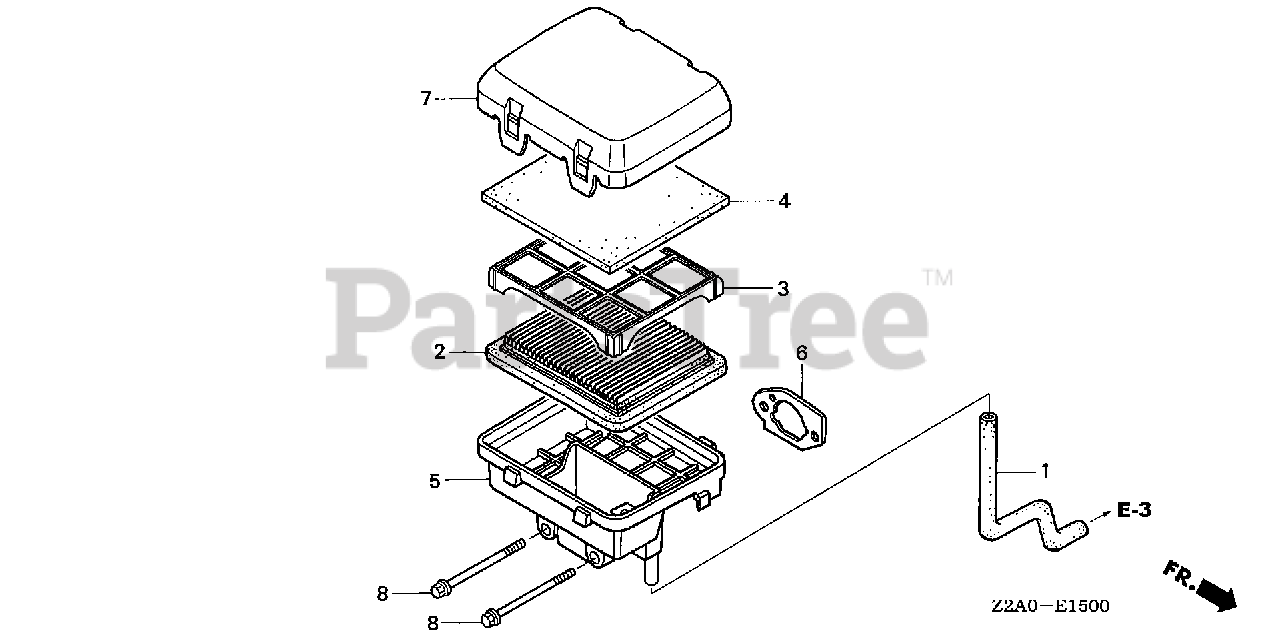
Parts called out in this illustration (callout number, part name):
1	TUBE, BREATHER
2	ELEMENT, AIR CLEANER (TOYO ROKI)
3	GRID, AIR CLEANER
4	FILTER (OUTER) (WET)
5	HOUSING, AIR CLEANER
6	GASKET, AIR CLEANER
7	COVER, AIR CLEANER (DUAL)
8	BOLT, FLANGE (6X112) (CT200)
